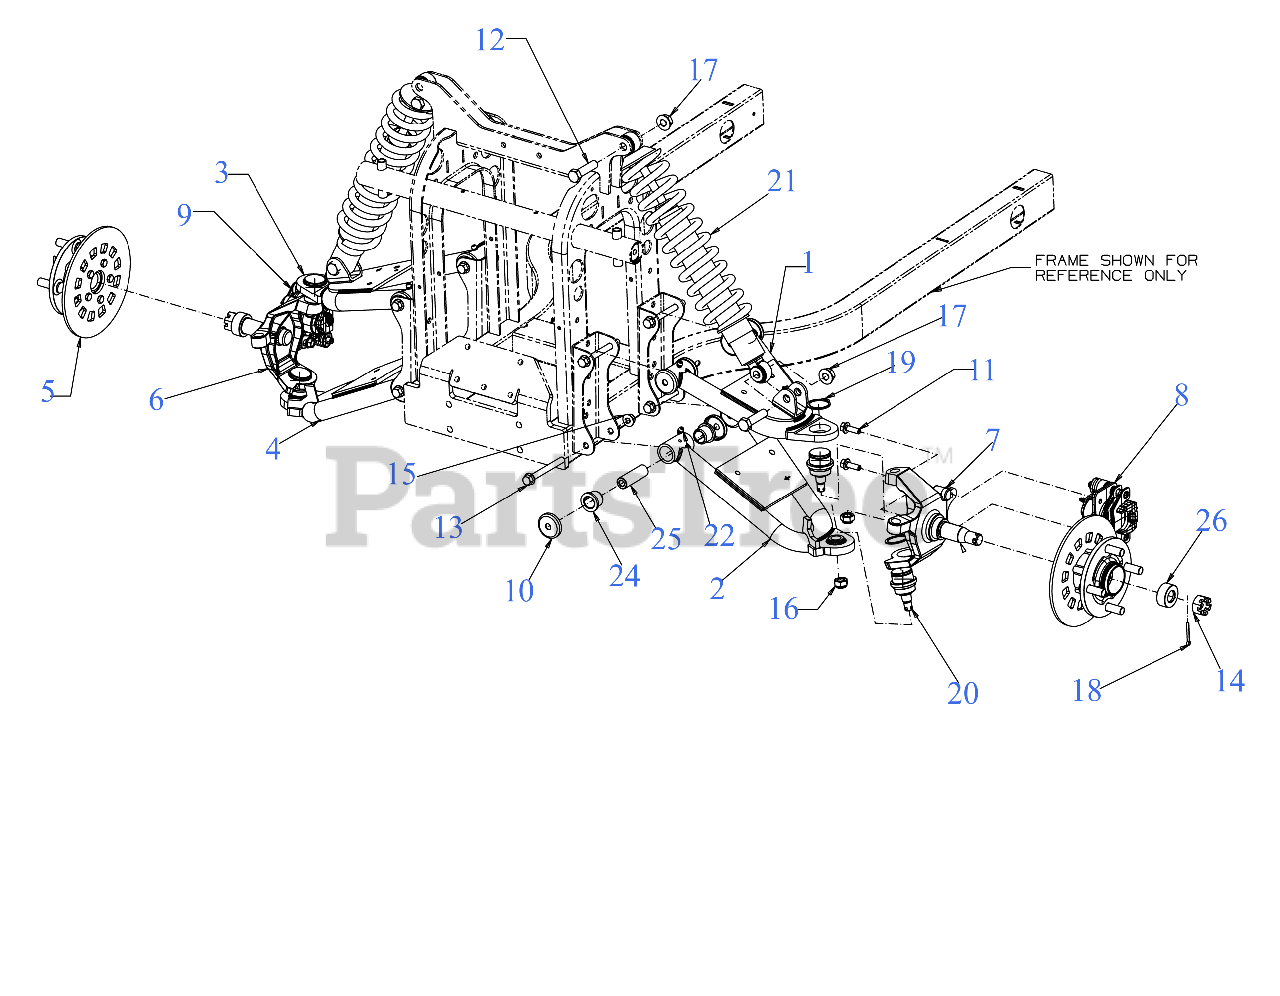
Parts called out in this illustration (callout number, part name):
5	WHEEL HUB ASSEMBLY
6	RIGHT FRONT KNUCKLE ASSEMBLY
7	LEFT FRONT KNUCKLE ASSEMBLY
8	CALIPERBRAKE ASSEMBLY- FRONT (RH)
9	CALIPERBRAKE ASSEMBLY- FRONT (LH)
10	PIVOT ARM BRACKET
11	SCREW M8 x 1.25 x 25MM GR8.8
12	SCREW 1/2-13 x 2 GR5
13	HEX FLANGE BOLT 3/8-16:3.50
14	HEX NUT CASTLE 3/4-16
18	COTTER PIN-5/32 DIA
19	RETAINING RING
20	BALL JOINT
21	FRONT SHOCK ABSORBER
22	GREASE FITTING
24	FLANGE BEARING .75 x .993
25	SPACER .385 x .75 x 1.873
26	SPACER .77 x 1.45 x .630
